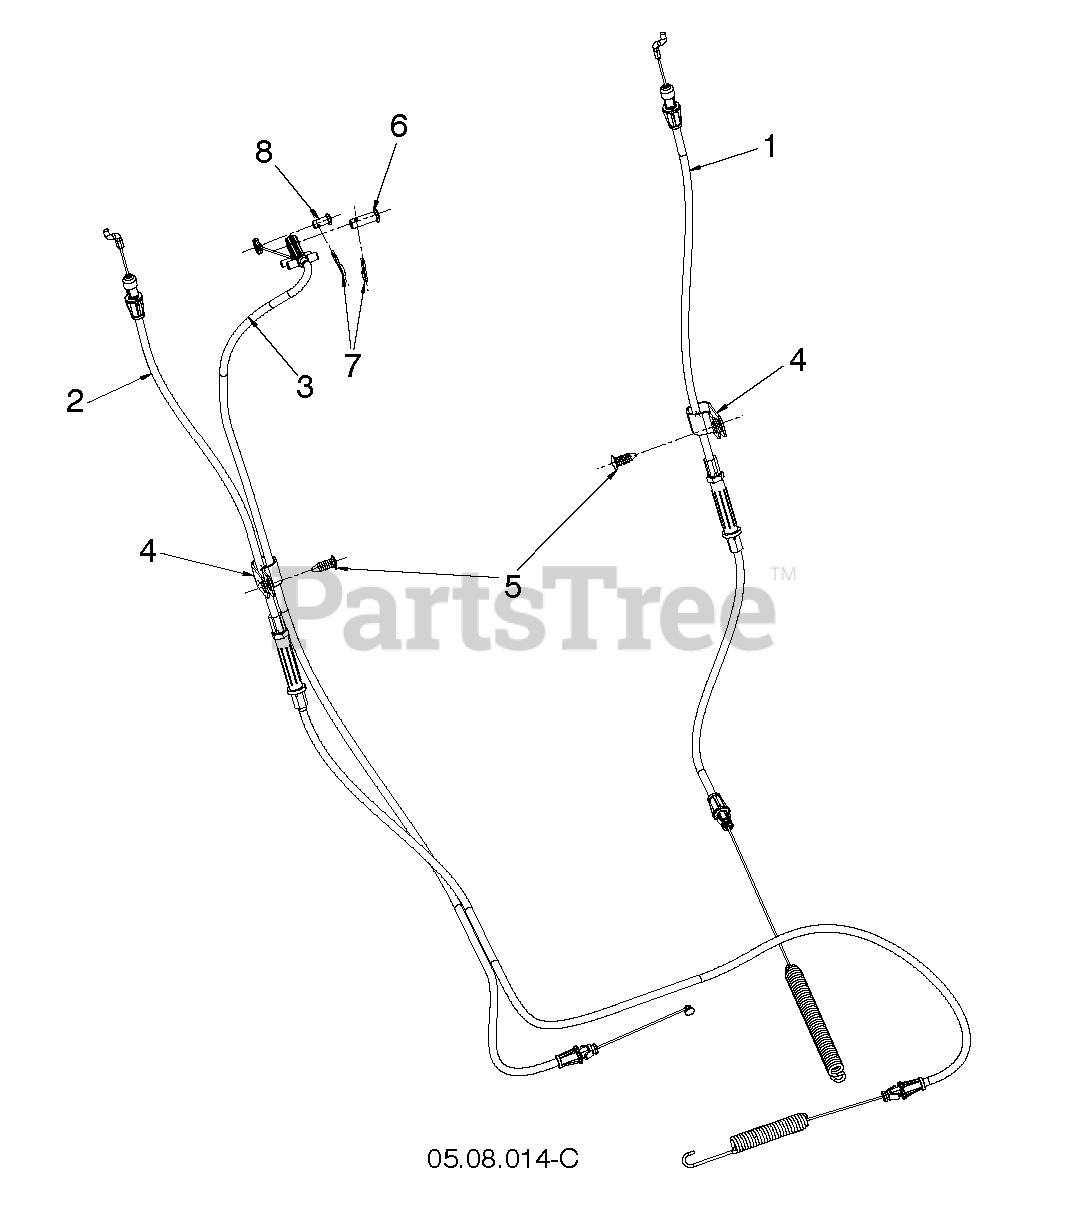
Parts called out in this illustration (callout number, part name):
1	CABLE.DRIVE CONTROL W/ADJ
2	CABLE.CONTROL.AUGER
3	CABLE.CONTROL.SPEED.DSST.OPP
4	CLIP.CABLE.BLK
5	FASTENER.PUSH.O.250X0.783
6	PIN CLEVIS 5/16X.875
7	HAIRPIN.SOFT.ZINC.059X1.125
8	PIN CLEVIS .25 X .31
